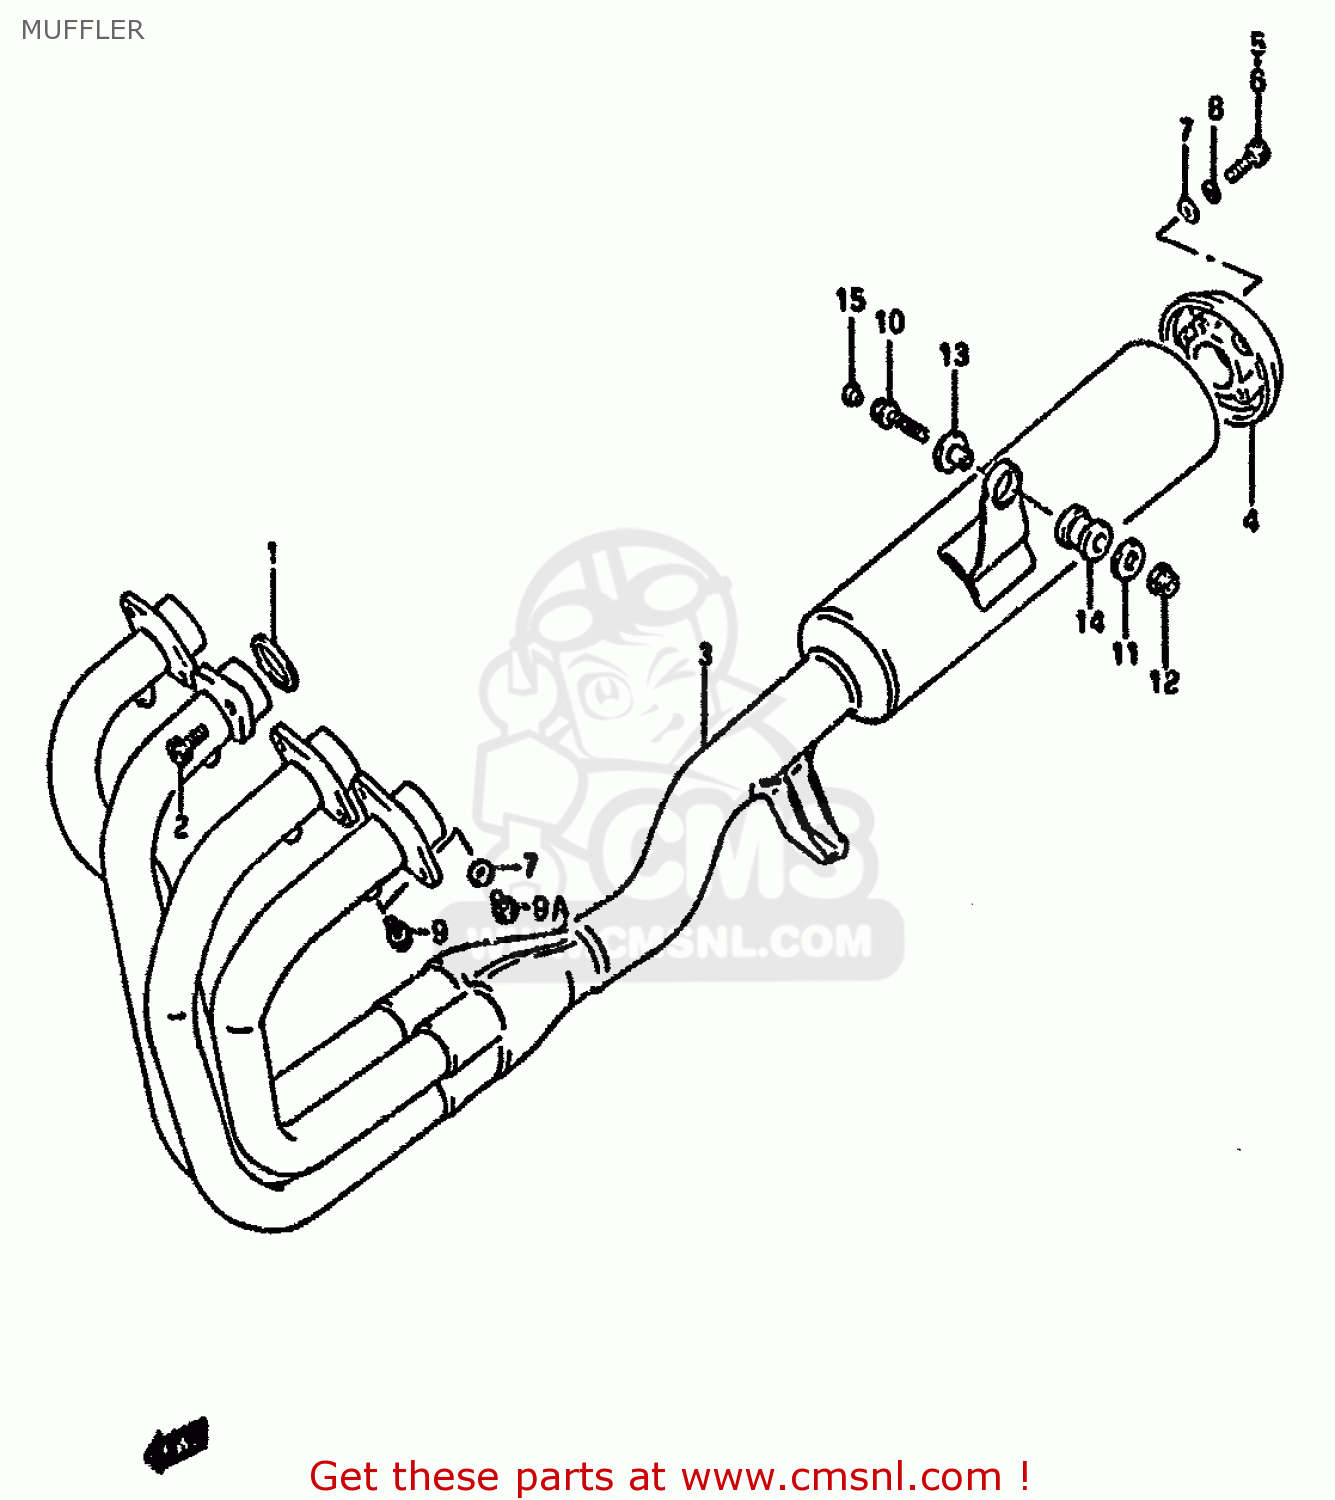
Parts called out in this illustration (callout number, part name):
1	GASKET,EXHAUST PIPE (NAS)
2	BOLT 8X23
3	MUFFLER ASSY
4	COVER,MUFFLER
5	BOLT(6X10)
6	BOLT
7	WASHER(7X12X1)
8	WASHER
9	BOLT,HOSE JOINT
9A	BOLT(6X10)
10	BOLT
11	WASHER (8.5X29X1.6)
12	NUT
13	SPACER(8.6X12X24.2)
14	CUSHION
15	CAP(OD:10)
